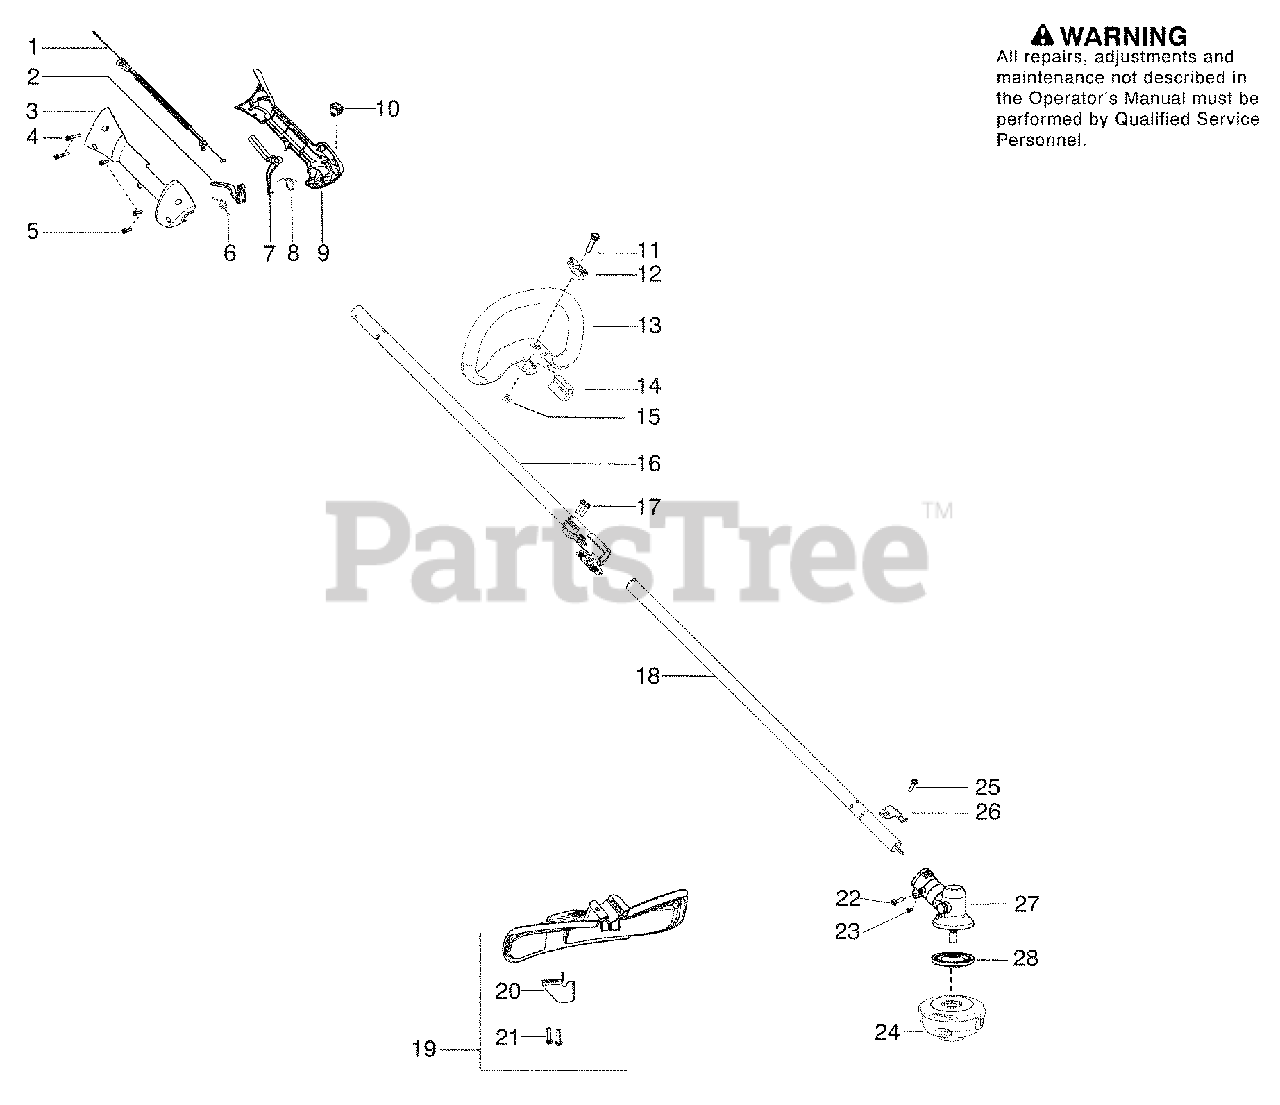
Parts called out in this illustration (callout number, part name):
1	Assy-Cable/Wire Harness
3	Housing-Throttle (RH)
6	Spring-Trigger
7	Lockout-Throttle
8	Spring-Lockout
9	Housing-Throttle (LH)
10	Kit-Switch
13	Assy - Loop Handle
15	Nut - Square M6
16	Kit-Driveshaft Upper
18	Kit-Lower Shaft
19	Kit-Shield
20	Limiter-Line
24	Assy-T25 Cutting Head
26	Bracket-Shield
27	Assy-Gearbox
28	Driver Disc
